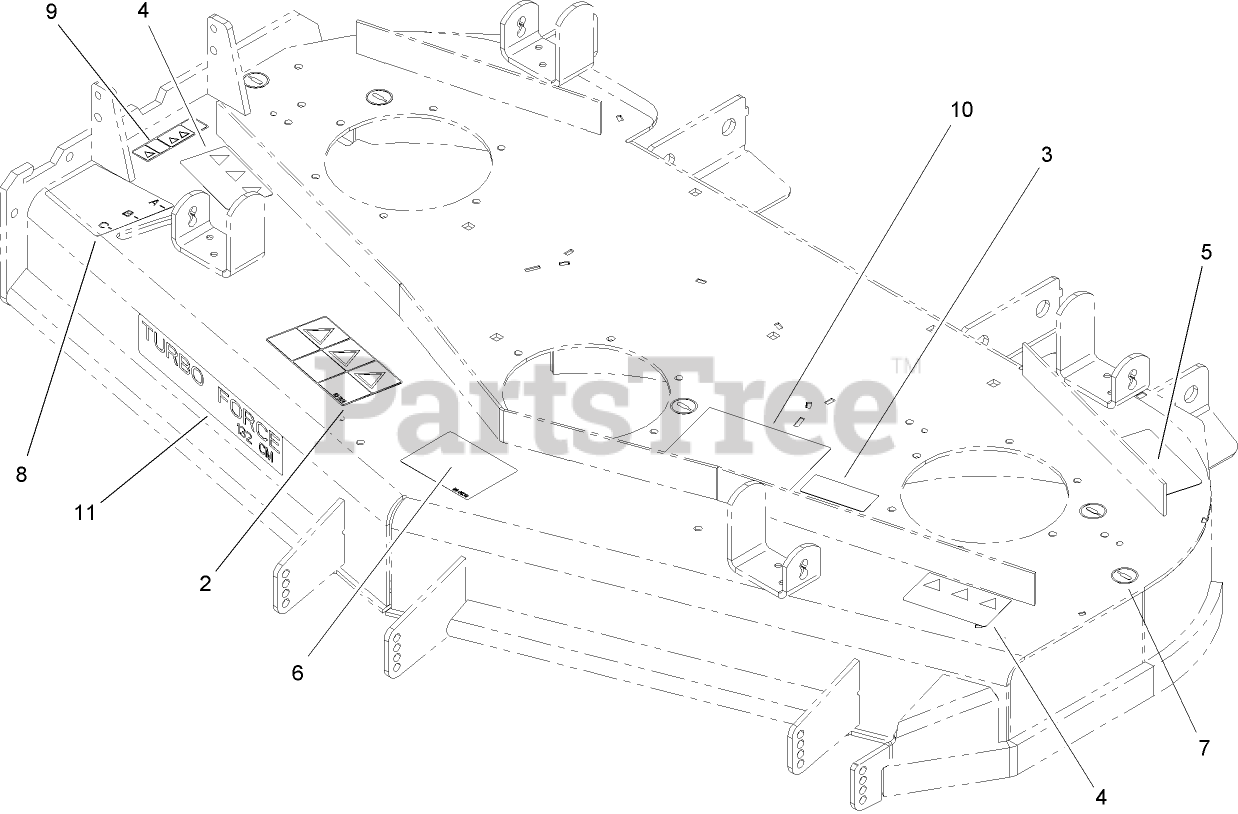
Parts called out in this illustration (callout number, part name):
2	DECAL-DANGER
3	DECAL-WARNING
4	DECAL-DANGER
5	DECAL-TORQUE, BLADE BOLT
6	DECAL-ANTI SCALP
7	DECAL-GREASE
8	DECAL-ADJUSTMENT, BAFFLE
9	DECAL-WARNING, DEFLECTOR
10	DECAL-SERVICE AID
